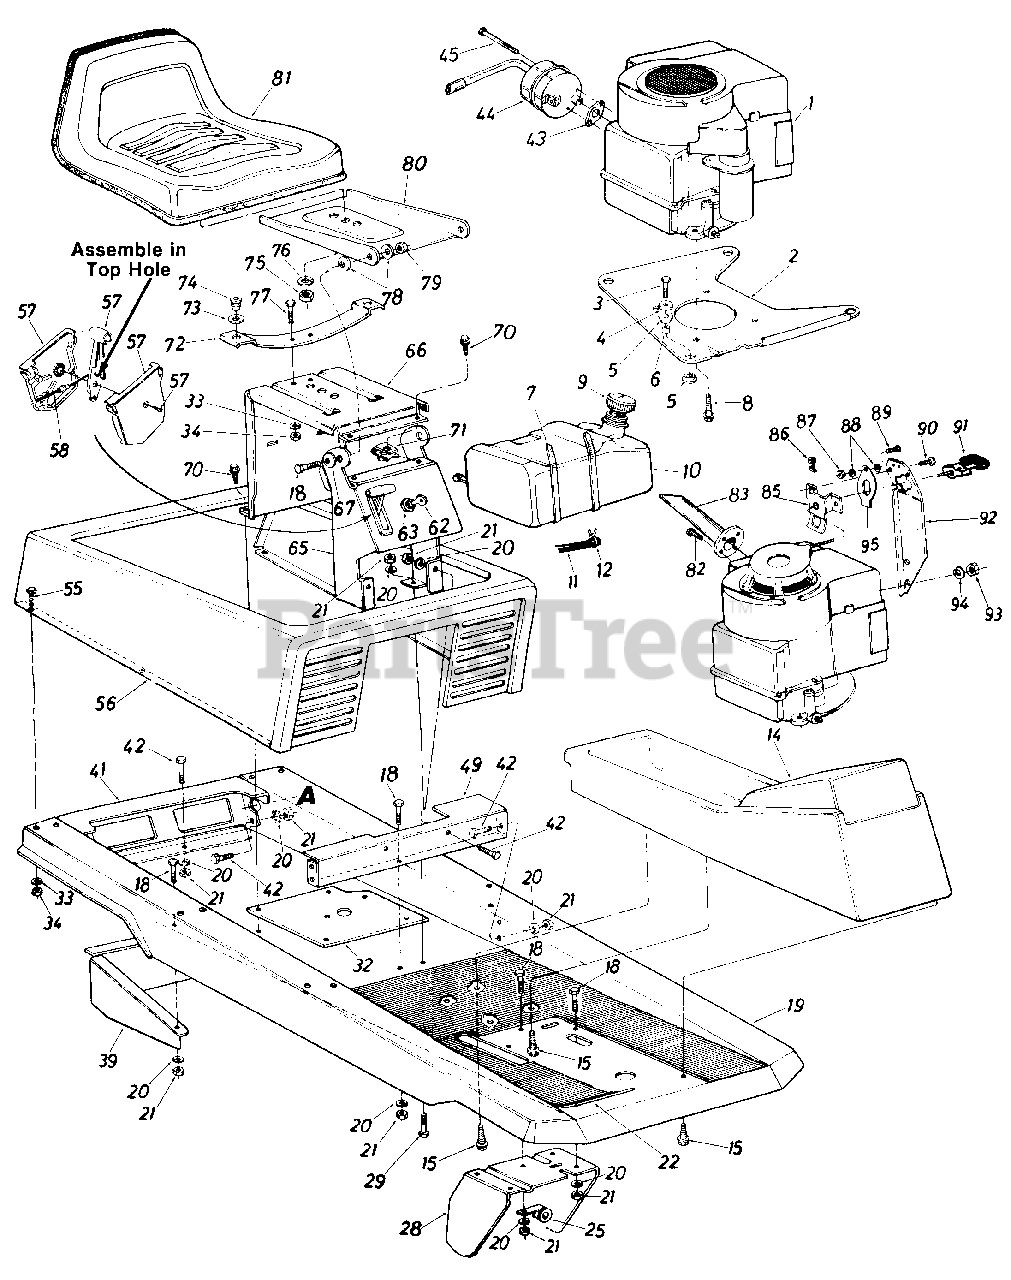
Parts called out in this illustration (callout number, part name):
1	Engine
2	Engine Mounting Plate
3	Hex Bolt 5/16-24 x 1.25" Lg.
4	Fl-Wash. .330" I.D. x 1.125" O.D.
5	Engine Mounting Grommet
6	Spacer .315" I.D. x .50" O.D. x .520" Lg.
7	Cable Tie
8	Hex Wash Hd. Self-Tap Scr. 3/8-16 x 1.25" Lg.
10	Fuel Tank
11	Gas Line
12	Hose Clamp .406" Dia.
14	Front Console
15	Plastite Scr. 5/16" x 1.25" Lg.
18	Hex Bolt 5/16-18 x .75" Lg.*
19	Main Frame
20	L-Wash. 5/16" I.D.*
21	Hex Nut 5/16-18 Thd.*
28	Clutch-Brake Pedal Ass'y.
29	Hex Bolt 5/16-18 x .62" Lg*
32	Mounting Brkt. Variable Speed Pulley
33	L-Wash. 1/4" I.D.*
34	Hex Nut 1/4-20 Thd.*
43	Exhaust Gasket
44	Muffler Ass'y.
45	Shld. Bolt
49	Seat Support & Frame Brkt.
55	Hex Bolt 1/4-20 x .50" Lg.*
56	Engine Cover Ass'y.
57	Throttle Control Box Ass'y.
58	Throttle Control Wire
62	Ignition Key
63	Ignition Switch
65	Front Seat Bracket
66	Rear Seat Bracket
67	Bell-Wash. .345" I.D. x .88" O.D.
70	Hex Wash Hd. Scr. 5/16-18 x .75"
71	Palnut Lug 5/16-18 Thd.
72	Seat Spring
73	Fl-Wash. .531" I.D. x .930" O.D.
74	Grommet
75	Hex Nut 1/2-13 Thd.*
76	L-Wash. 1/2" I.D.*
77	Hex Bolt 1/4-20 x .62" Lg.*
78	Bell-Wash. .345" I.D. x .88" O.D.
79	Hex Cent. L-Nut 5/16-18 Thd.
80	Seat Pivot Bracket
81	Seat Ass'y. Comp.
82	Hex Wash. Hd. TT-Tap Scr. 8-32 x .50" Lg.
83	Exhaust Pipe Ass'y.
85	Switch Brkt. Ass'y.
86	Speed Nut #10-24 U-Type
87	Hex Nut #10-24 Thd.*
88	Fiber Washer
89	Truss Mach. Scr. #10-24 x .62" Lg.*
90	Truss Mach. Scr. #10 x .50" Lg.*
91	Plastic Handle
92	Rope Handle Bracket
93	Hex N ut 5/16-18 Thd.*
94	L-Wash. 5/16" I.D.*
95	Switch Spring
